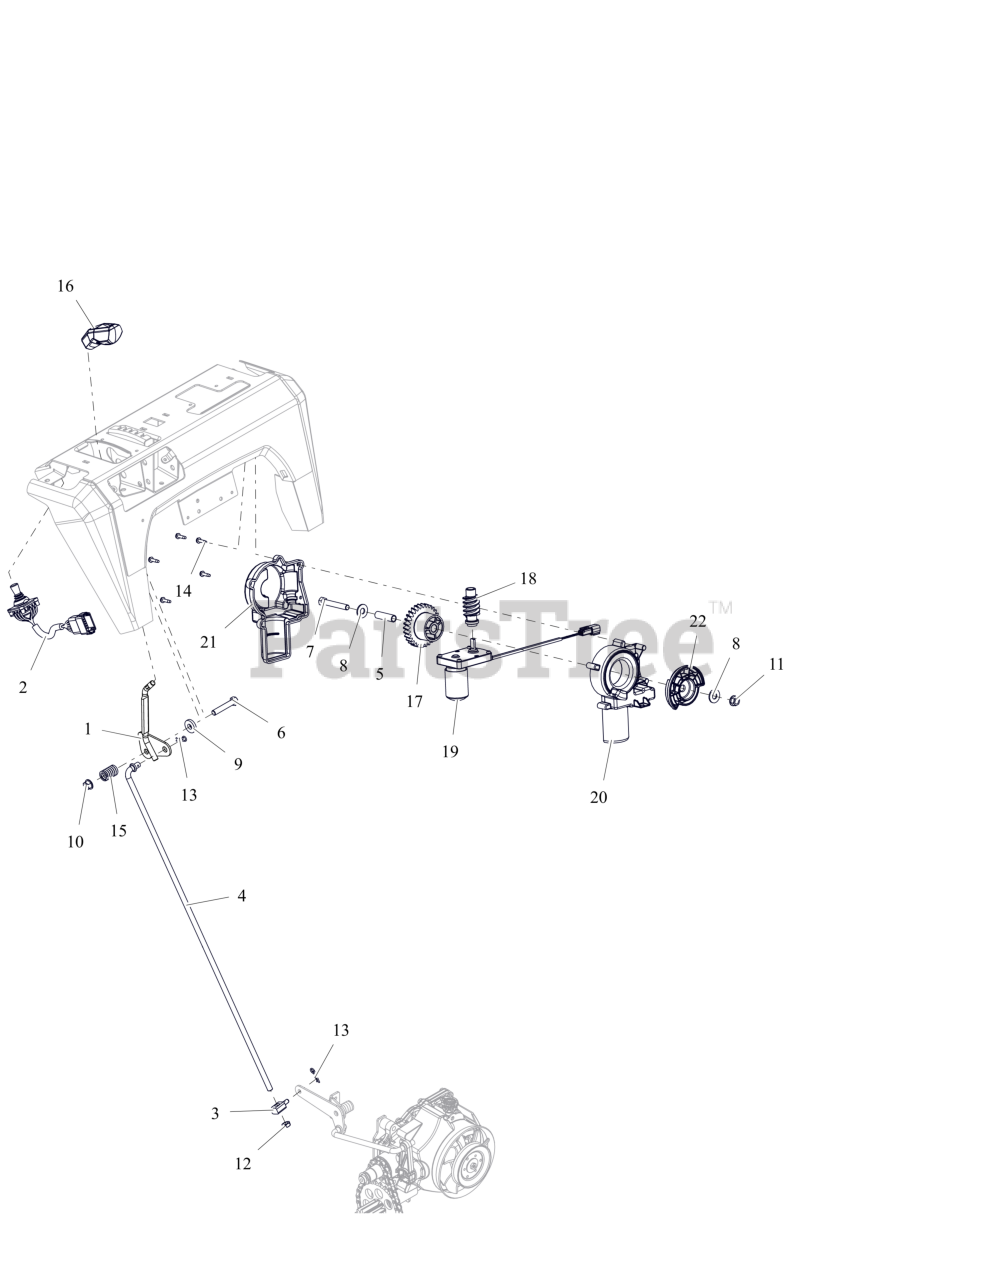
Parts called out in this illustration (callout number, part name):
1	WELDMENT,LG DASH SPEED CONTROL
2	HARNESS, JOYSTICK
3	PIVOT,SHIFT ROD .375-16(TRUNN)
4	ROD, SHIFT - PRO
5	BSHG-SLV- .391X.500X.1.750
6	BLT,HEX .38-16X2.00 G5 ZCC
7	BLT, HEX .38-16X2.50 G5 ZCC
8	WSHR,FLT .438X1.00X.083 ZCC
9	WSHR, FLT .406X1.00X.188 ZCC
10	NUT-LK-TOP-FLG .38-16 ZC120
11	NUT-LK-CTR-FLG .375-16 GF ZCC
12	NUT-JAM .375-16 G2 ZCC
13	PIN, HAIR #213 .08X1.19 ZCC
14	SCR- TAP #10-32X.750 T23 ZCC
15	SG-COMP .125X.781X1.250
16	KNOB, CONTROL
17	GEAR, HELICAL
18	WORM, DRIVE
19	MOTOR, E-CHUTE
20	ENCLOSURE, CAP ACTUATION (MALE)
21	ENCLOSURE, CAP ACTUATION (FEMALE)
22	ADAPTOR, CAM
